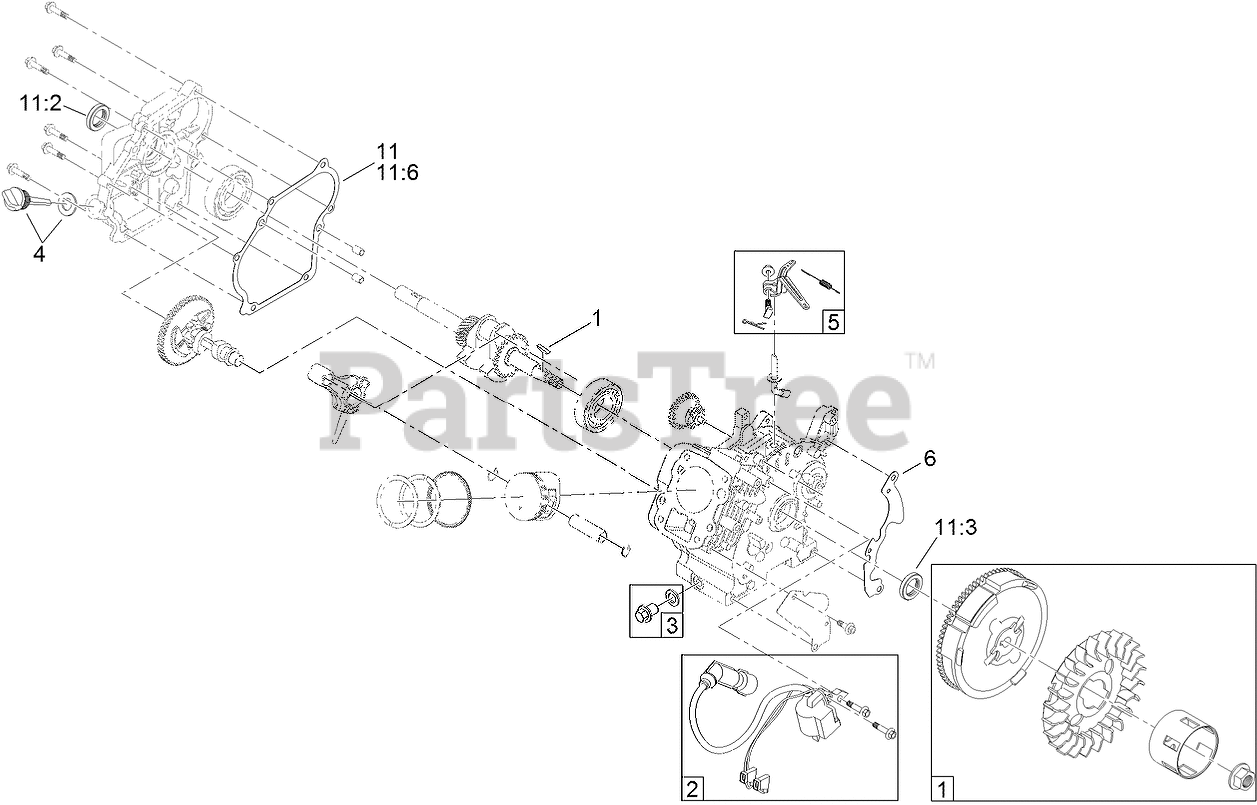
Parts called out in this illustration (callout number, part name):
1	FLYWHEEL AND FAN KIT
2	IGNITION KIT
3	DRAIN PLUG KIT
4	DIPSTICK AND O-RING KIT
5	GOVERNOR KIT
6	BLOWER SHROUD KIT
11	GASKET, SEAL AND O-RING KIT
11:1	Gasket-Exhaust
11:2	Seal-Oil
11:3	Seal-Oil
11:4	GASKET-COVER, VALVE
11:5	GASKET-HEAD, CYLINDER
11:6	GASKET-COVER, CRANKCASE
11:7	GASKET-INSULATOR
11:8	INSULATOR-CARBURETOR
11:9	GASKET-CARBURETOR
